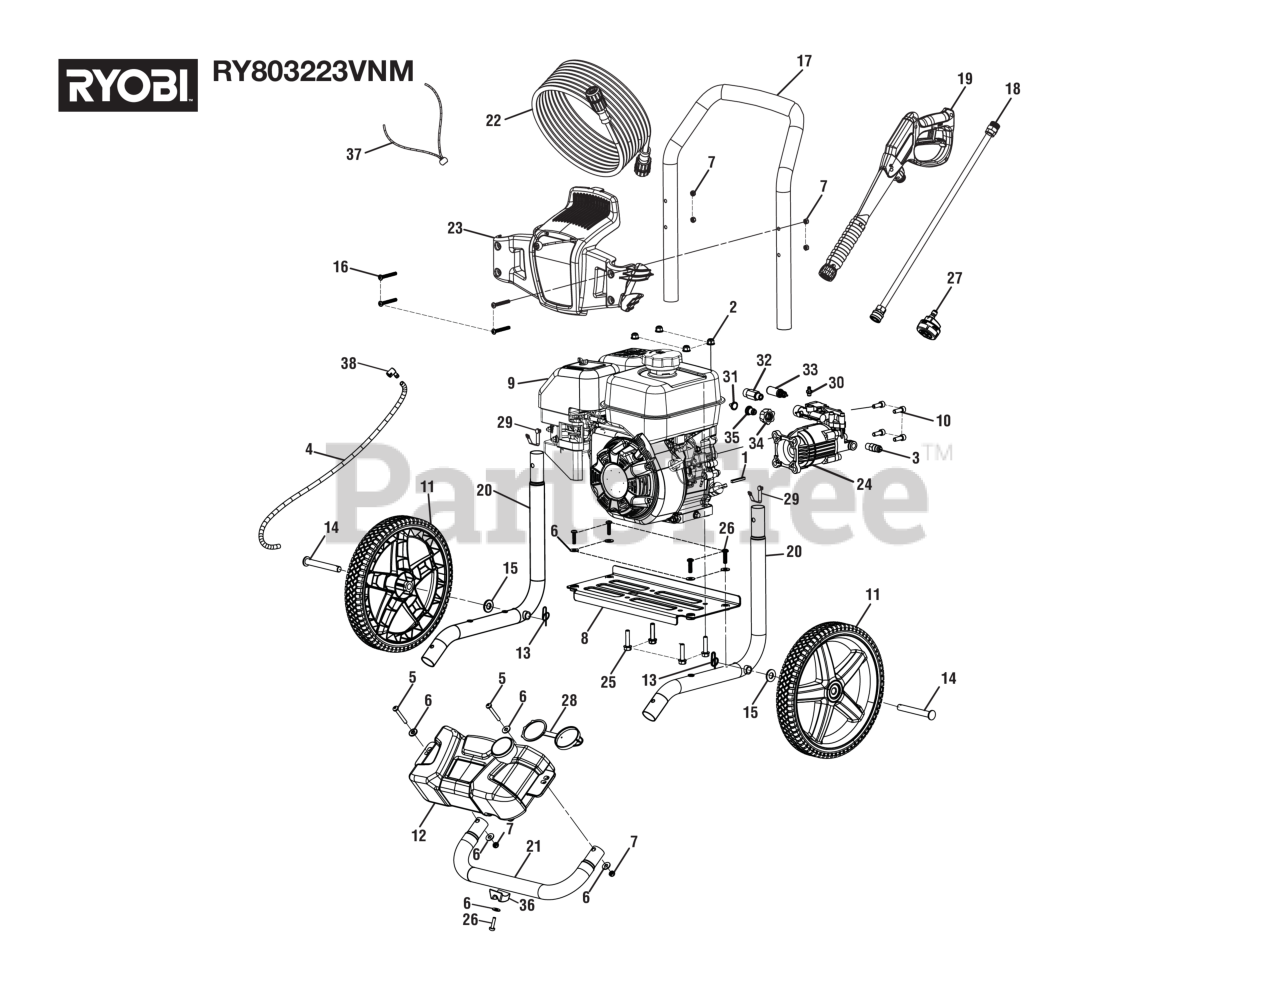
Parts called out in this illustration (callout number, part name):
1	Output Shaft Key (3/16 in. x 40 mm)
2	Lock Nut (M8 x 1.25 mm, Flange)
3	Thermal Release Valve.
4	Chemical Siphon Tube
5	Screw (M6 x 1 x 48 mm, T30 Torx Pan Hd.)
6	Washer (1/4 in.)
7	Lock Nut (M6 x 1)
8	Engine Plate
9	Motor Assembly
10	Screw (5/16-24 x 23 mm, Hex Soc. Cap Hd.)
12	Soap Tank
13	Hitch Pin
15	Washer (1/2 in.)
16	Bolt (M6 x 48 mm, Button Hd.)
17	Handle Assembly
18	Extension Wand
19	Trigger Handle
20	Frame Assembly
21	Front Frame Assembly (Inc. Key No. 33)
22	Hose (35 ft.)
23	Performance Panel
24	Pump (Inc. Key Nos. 57-62)
25	Bolt (M8 x 36 mm, Hex Flange Hd.)
26	Screw (M6 x 1.25in., T30 Torx Pan Hd.)
27	5-in-1 Nozzle
28	Detergent Tank Cap
29	Lock Button w/Spring Clip.
30	Detergent Injector Assembly
31	Filter Screen (Pump Inlet)
32	Outlet Tube
33	Unloader Valve Assembly
34	Inlet Filter Adapter/Brass Insert
35	Inlet Filter Connector
36	Rubber Foot
37	Bungee Cord and Bead Assembly
38	Soap Hose Inlet Adapter
